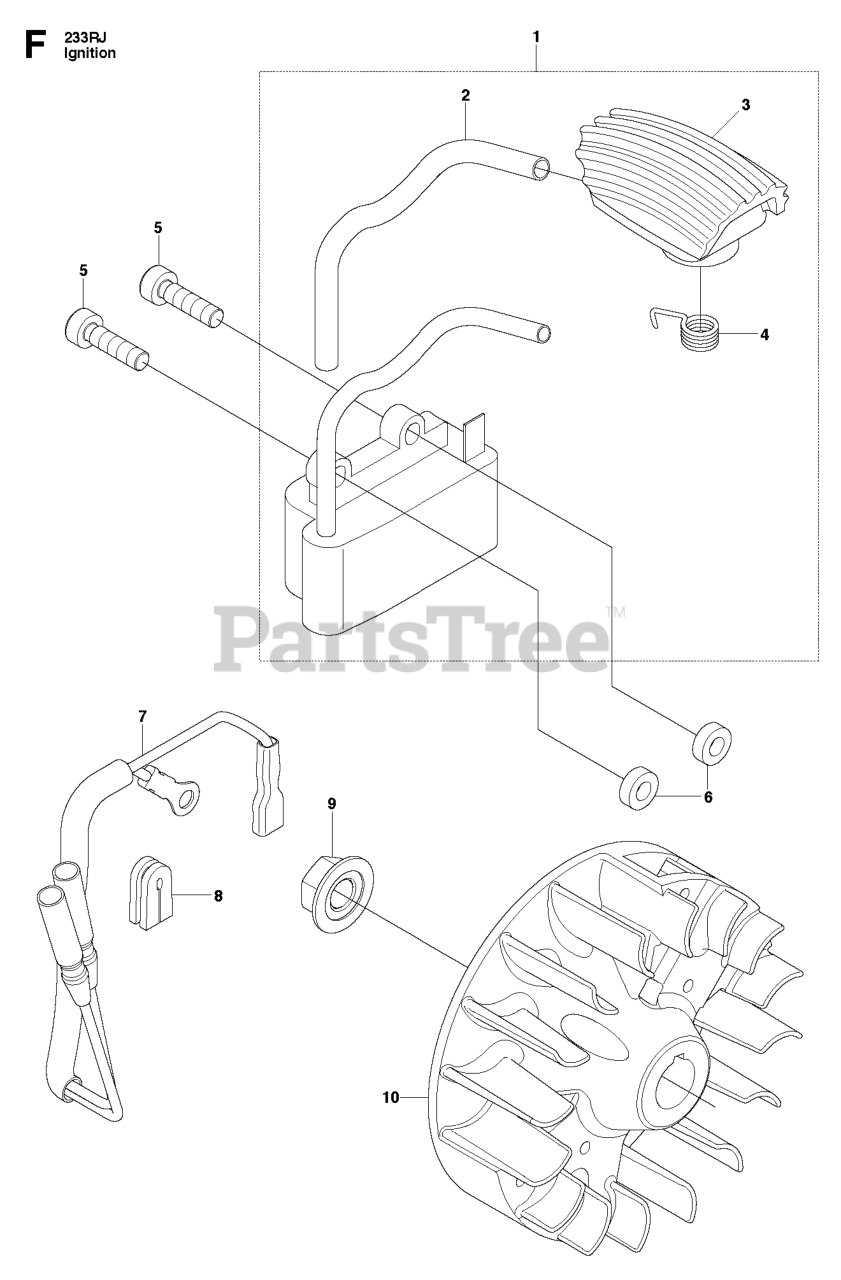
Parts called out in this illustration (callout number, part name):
1	COIL-A
2	TUBE (RPLS 261671510,1511)
4	SPRING
5	BOLT TORX M4XL16 T27
6	SPACER
7	CORD COMP.
9	RP NUT
10	COVER,TRF (RPLS 848F6012D1)
